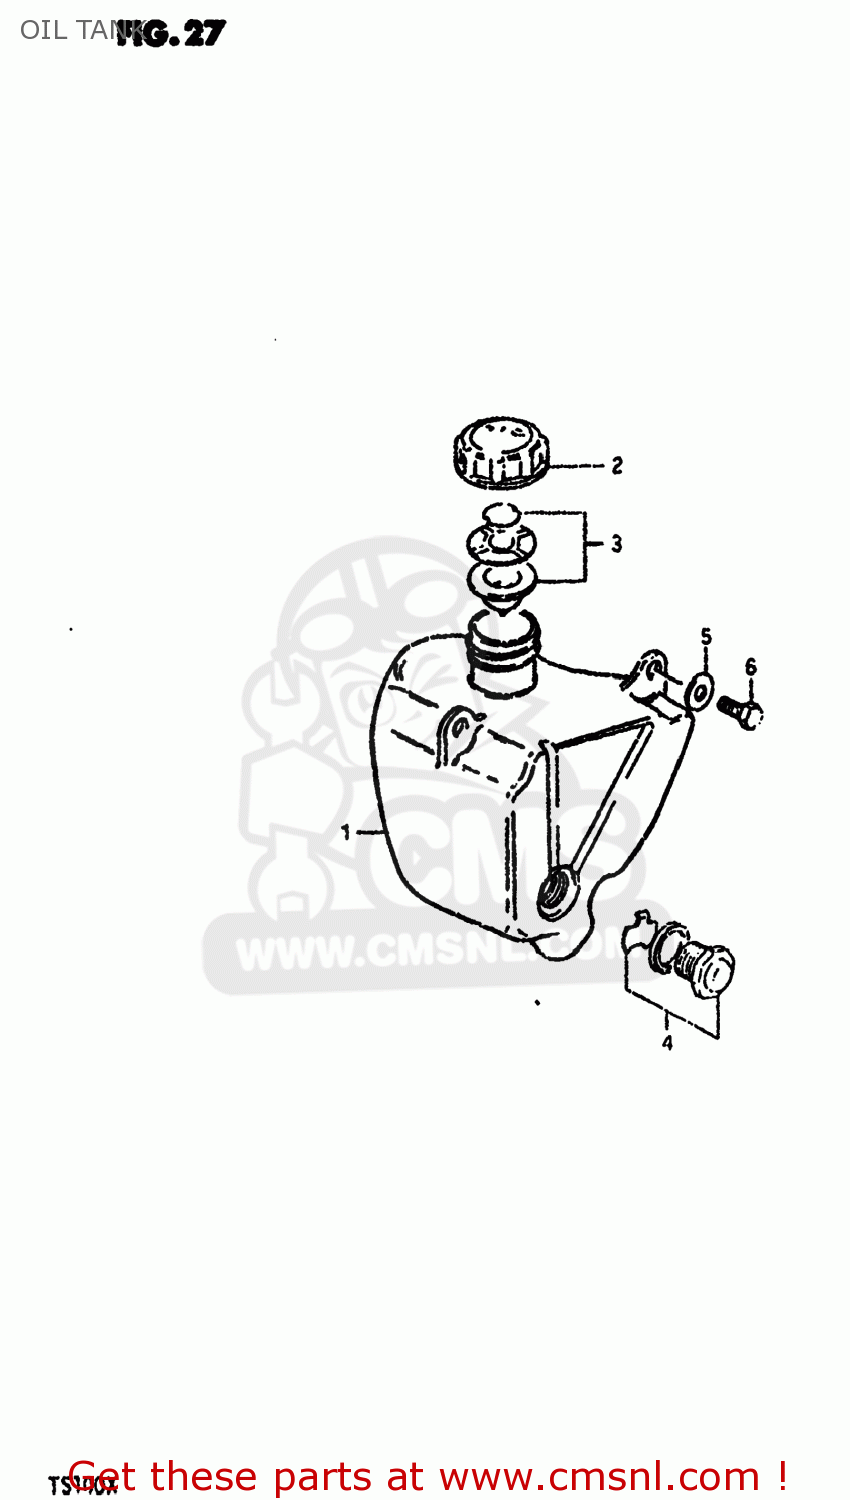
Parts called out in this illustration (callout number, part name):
1	TANK,OIL
2	CAP,OIL TANK
3	GASKET SET (NAS)
4	LENS SET,OIL LEVEL
5	WASHER
6	BOLT, UPPER
